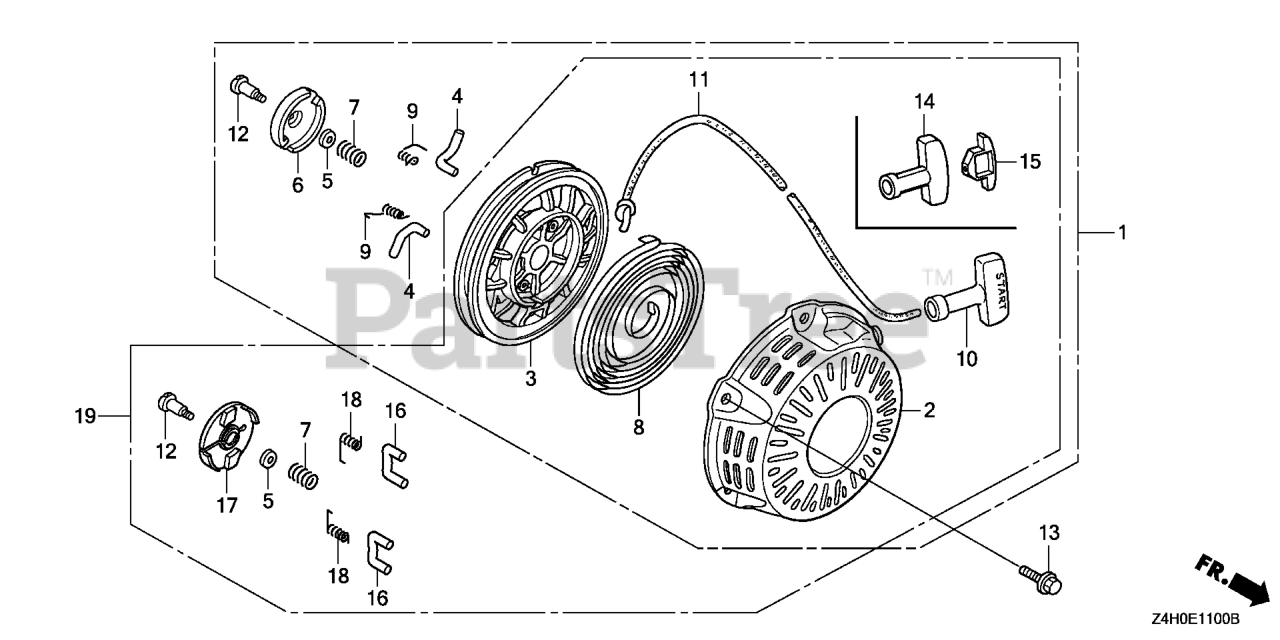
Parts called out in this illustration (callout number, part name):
2	CASE, RECOIL STARTER *R280* (POWER RED)
3	REEL, RECOIL STARTER (BLACK)
5	PLATE, FRICTION
7	SPRING, FRICTION
8	SPRING, RECOIL STARTER
11	ROPE, RECOIL STARTER (#5X55")
12	SCREW, SETTING
13	BOLT, FLANGE (6X8)
14	KNOB, RECOIL STARTER
15	KNOB, REINFORCEMENT
16	RATCHET, STARTER
17	GUIDE, RATCHET
18	SPRING, RETURN
19	STARTER ASSY., RECOIL *R280* (COO)(FOR U.S.A.) (POWER RED)
